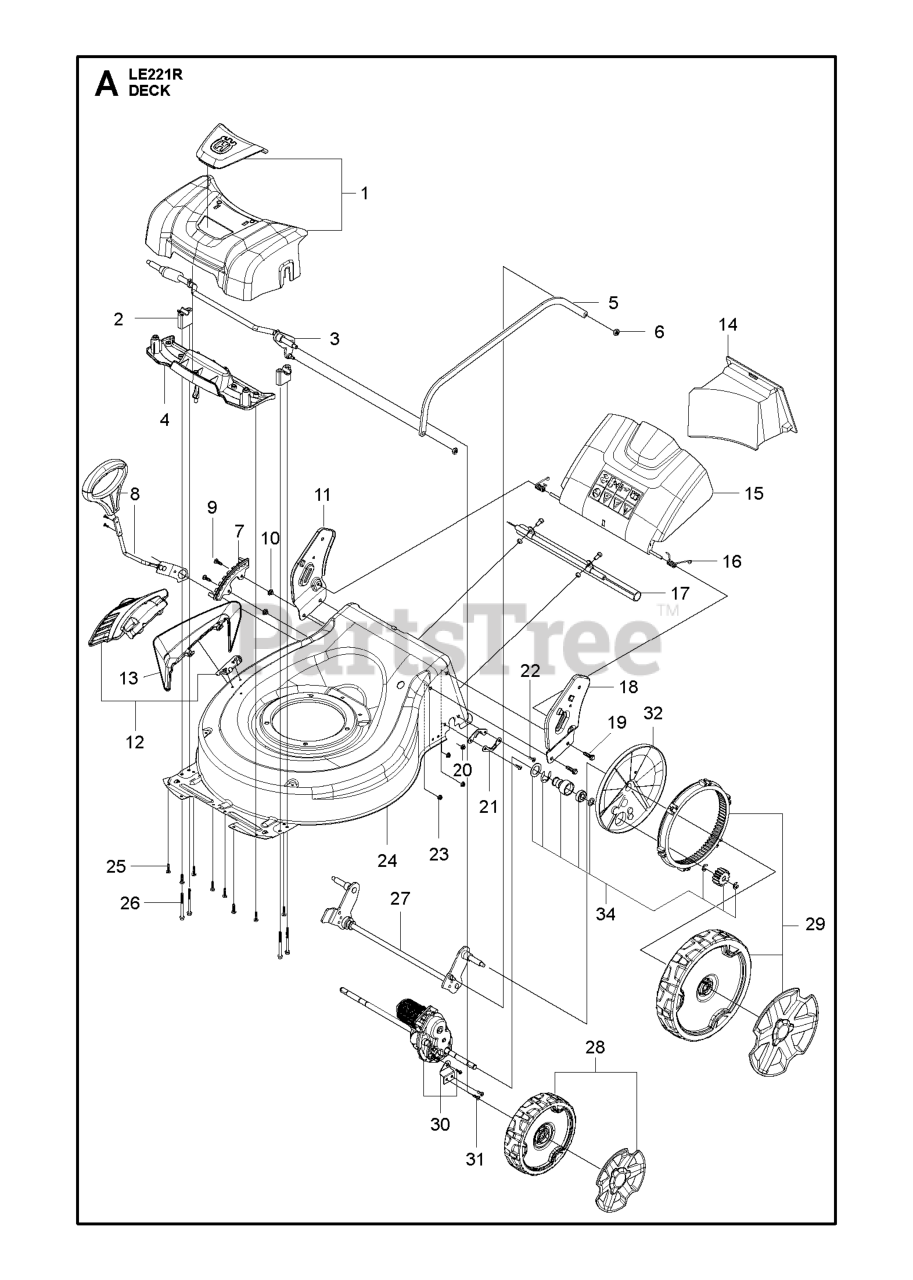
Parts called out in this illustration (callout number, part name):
1	FRONT COVER ASSY FRONT COVER U
2	BRACKET FRONT AXLE
3	WHEEL AXLE SUSPENSION FRONT
4	COVER FRONT COVER LOW
5	ROD SUSPENSION
6	LOCKING BOLT M6,GB889.1 #26800
7	HEIGHT ADJUST
8	LEVER ASSY HEIGHT ADJUSTMENT H
9	SCREW MACHINED DAYE# A26800201
10	LOCK NUT M6 LOCKING HEX FLANGE
11	HANDLE SUPPORT RIGHT
12	HATCH SIDE DISCHARGE
13	DEFLECTOR SIDE DISCHARGE
14	MULCH PLUG
15	HATCH REAR DISCHARGE
16	SPRING REAR DISCHARGE HATCH
17	FLAP REAR TAIL
18	HANDLE SUPPORT LEFT
19	BOLT M8*16 #26800606401
20	LOCK NUT M6 LOCKING HEX FLANGE
21	BRACKET REAR ASSY LE221R
22	SCREW M6*16 #26800204601
23	LOCKING BOLT M8,GB6187.1 #2680
24	CHASSIS DECK ASSY
25	SCREW SELF TAPPING DAYE# A2680
26	SCREW HEX FLANGE DAYE# A268006
27	WHEEL AXLE SUSPENSION REAR LE
28	WHEEL ASSY FRONT LE121P / LE22
29	WHEEL ASSY REAR LE221R
30	TRANSMISSION ASSY
31	BOLT M6*12,(GB5787-86)GB6674.1
32	DUST COVER 20 INCH MOWER
34	TRANSMISSION KIT BEARING AND P
